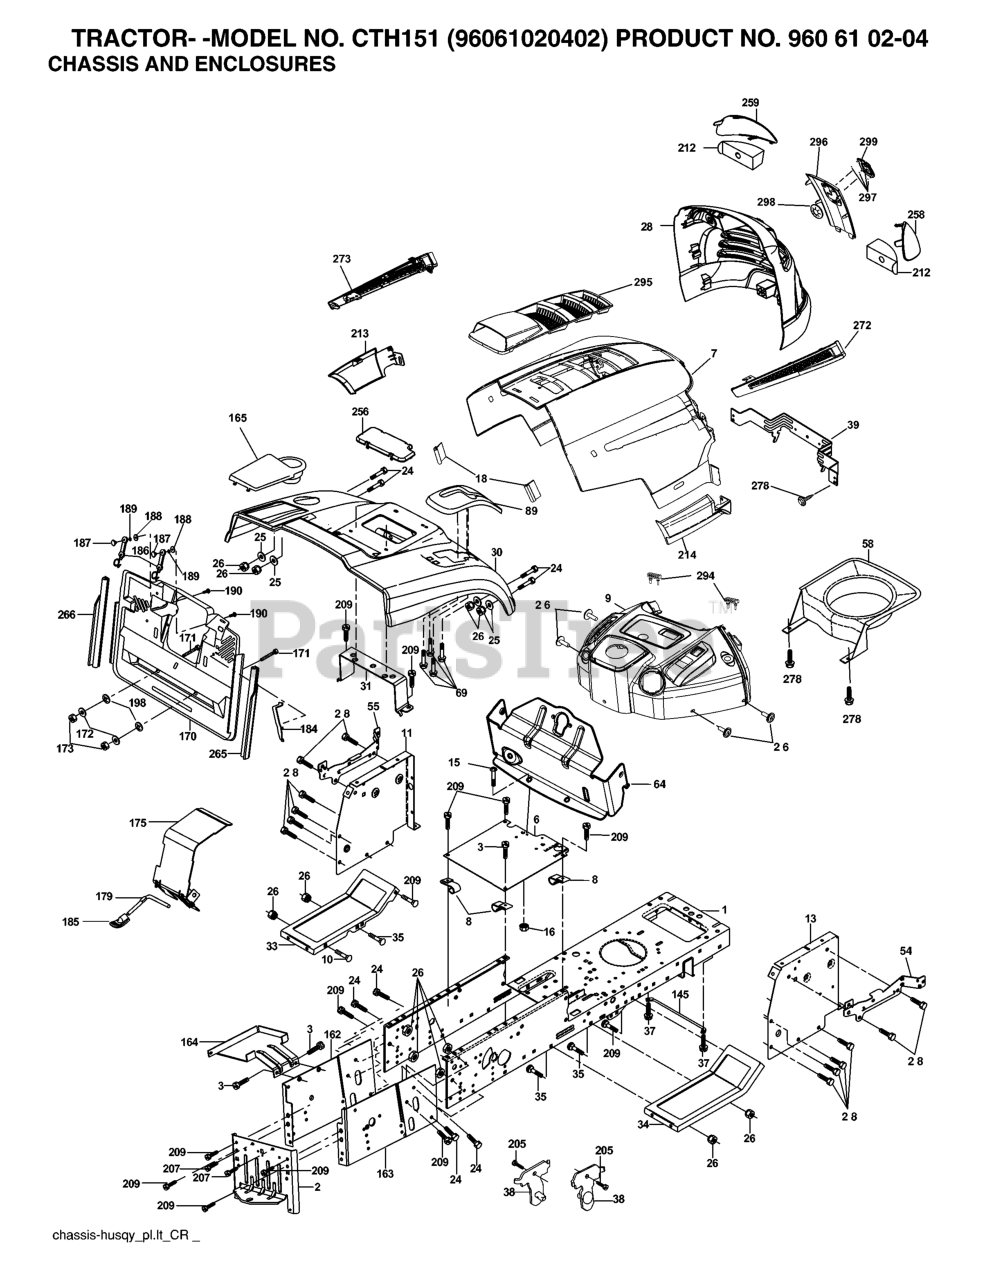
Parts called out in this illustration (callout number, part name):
2	DRAWBAR
3	SCREW 3/8-16X3/4
6	PLATE
8	CLIP,INSULATOR
10	BOLT D
11	PANEL.DASH.LH.LTX
13	PANEL ASM, DASH RH
15	Screw, Machine, Truss Head 5/16-18 UNC x 3/4
16	NUT
17	HOOD
18	BUMPER.HOOD.TEX.HUSQVARNA
24	BOLT
25	WASHER
26	NUT
28	RP GRILLE/LENS ASM.
30	CONSOLE.CRD.AUTO.GRY
31	BRACKET SUPPORT FENDER
33	FOOTREST PNT LH
34	FOOTREST PNT RH
35	BOLT
37	Screw 5/16-18 x 1/2 Hex, Self Tapping 5/16-18 x 1/2
38	BRACKET ASM PIVOT MOWER REAR
39	BRACKET PIVOT
69	SCREW.HI-LO.CONSOLE
89	CONSOLE.CRD.AUTO.GREY.2005
145	ROD.PIVOT.HOOD
162	BRACKET
163	BRACKET EXTEN CHASSIS RH CRD
165	RP.COVER.BATTERY.CRD.GREY
171	BOLT
172	WASHER
175	DOOR TRAP
179	ROD PIVOT FBI
184	BRACKET.ACTUATOR.BAGGER.SRD
186	LATCH ASSY
187	WELDNUT
189	LOCKWASHER #10
190	SCREW
205	SCREW LT
207	SCREW, 5/16-18 X 1/2
208	SCREW 3/8-16X1/2
209	SCREW, 3/8-16X3/4
212	INSERT REFLECTIVE
213	SKIRT SIDE LH
214	SKIRT SIDE RH
216	SCREW HEXWSHR 1/4-20X3/4
256	COVER FENDER CRD
258	LENS.HUSQVARNA LT.RH
259	LENS.HUSQVARNA LT.LH
265	SEALING
266	SEALING
272	VENT SIDE HOOD RH
273	VENT SIDE HOOD LH
278	SCREW
294	BUMPER DASH
295	VENT TOP HOOD
296	TRIM
297	CLIP.RETAINER.TINNER.
298	NUT PUSH M
299	RP LOGO
